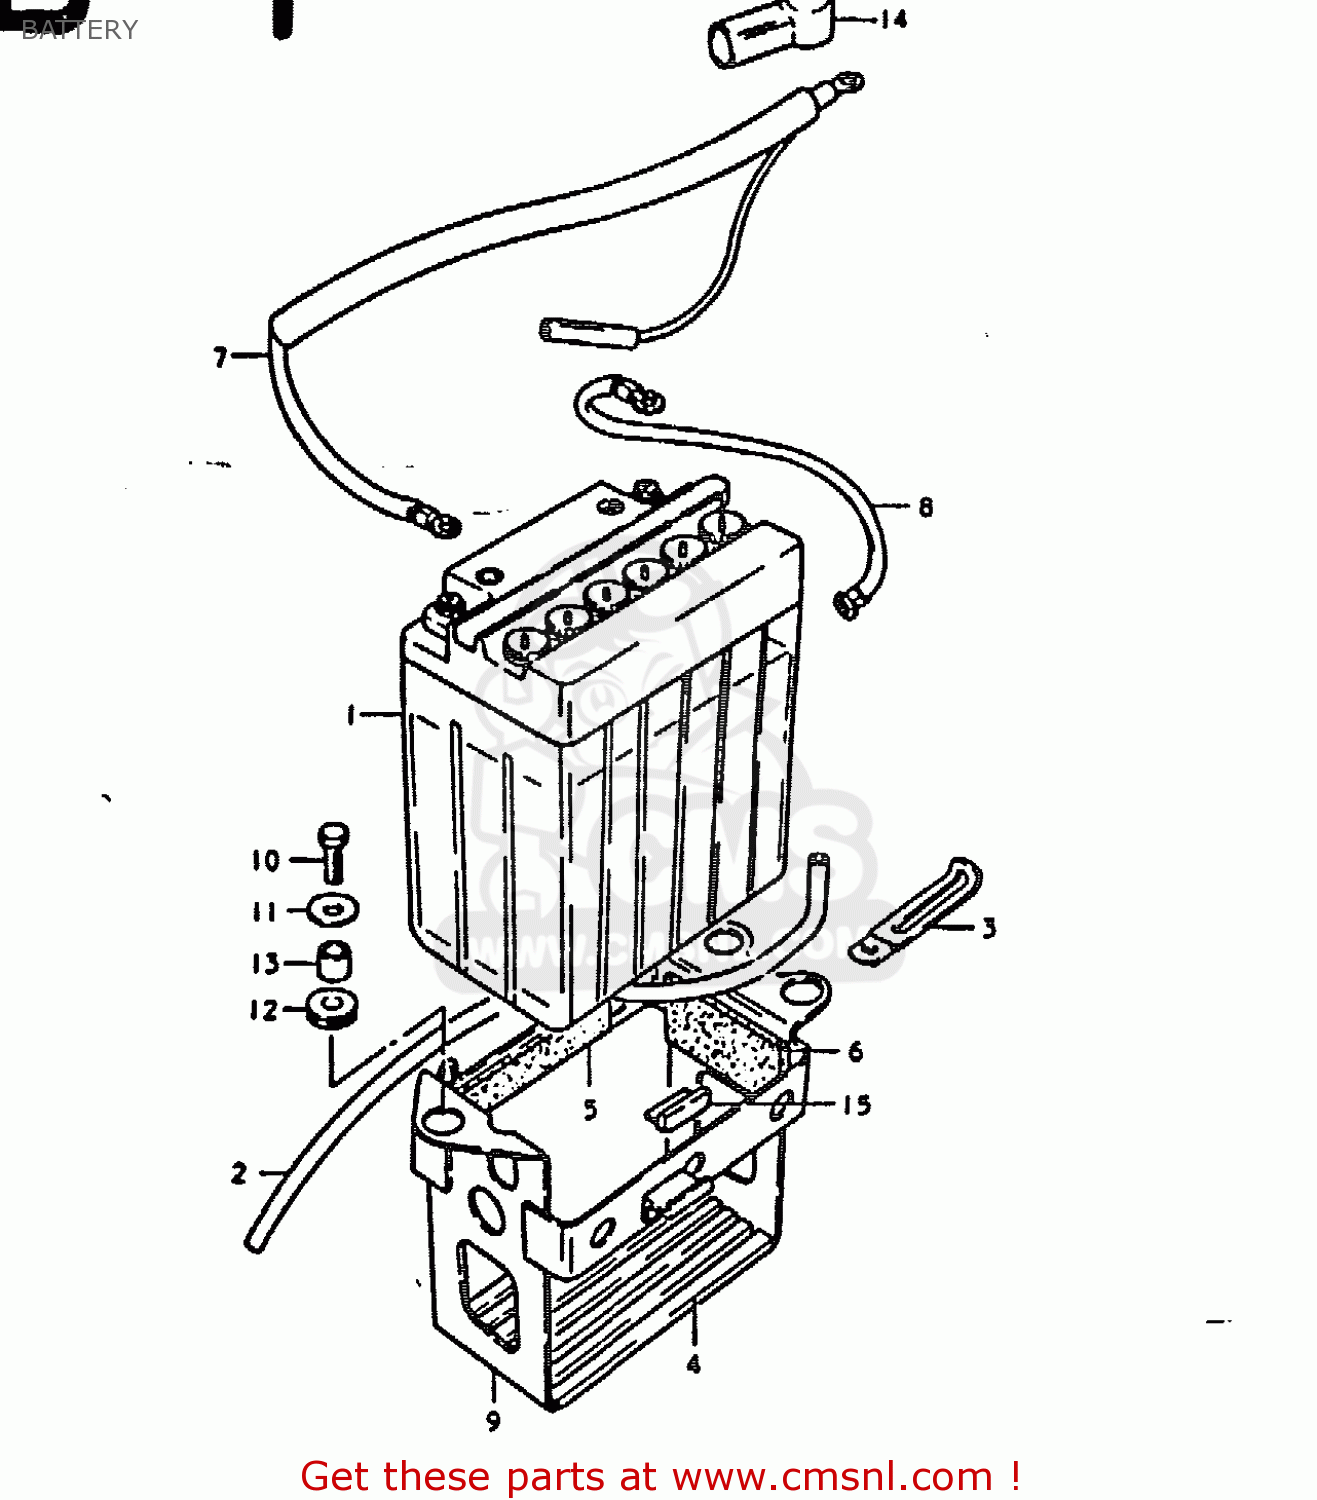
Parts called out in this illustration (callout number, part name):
1	BATTERY ASSEMBLY
2	HOSE,BATTERY EXHAUST
3	CLAMP L:35
4	PROTECTOR,BATTERY
5	PROTECTOR,20X9
6	CUSHION,BATTERY
7	WIRE,BATTERY PLUS
8	LEAD WIRE,BATTERY(-)
9	HOLDER,BATTERY
10	BOLT, UPPER
11	WASHER
12	CUSHION
13	SPACER(6.1X9X7.5)
14	CAP,TERMINAL
15	CUSHION,FRAME COVER
